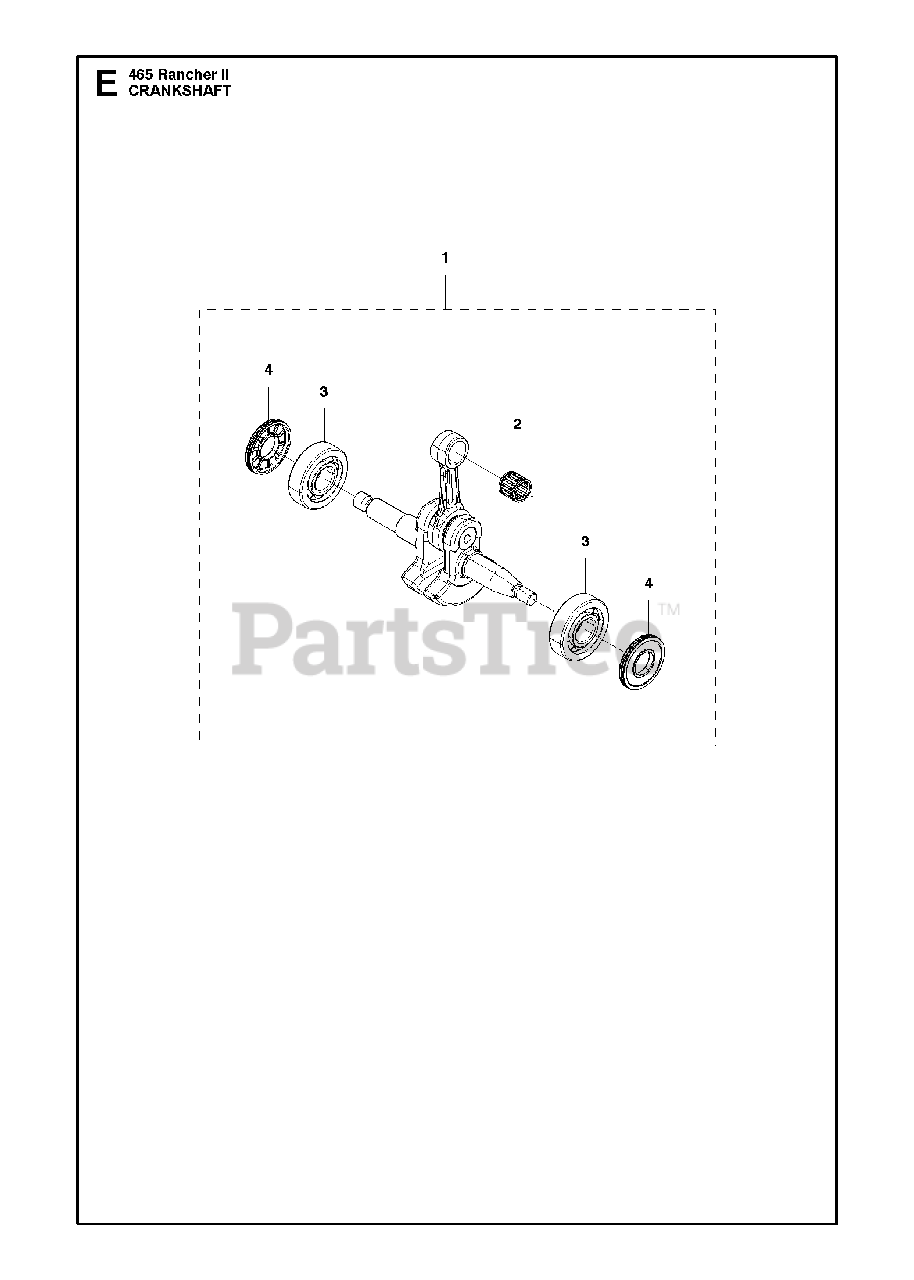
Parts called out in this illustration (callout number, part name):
1	CRANKSHAFT ASSY
2	SUPPORT BUSHING
3	BEARING
4	SEALING
